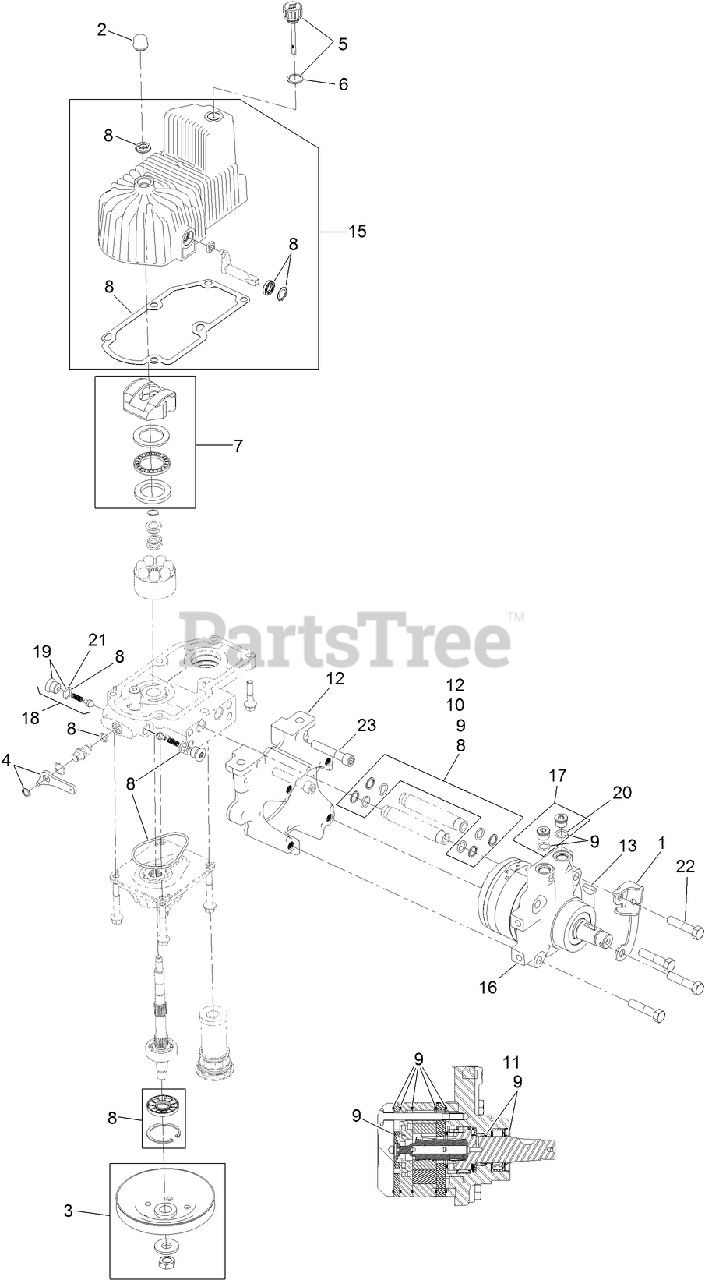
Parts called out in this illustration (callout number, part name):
1	BRACKET-ANCHOR, CABLE
2	COVER-SHAFT, HYDRO
3	PULLEY KIT
4	HANDLE-BYPASS VALVE, HYDRO
5	DIPSTICK-HYDRO W/GASKET
6	GASKET-DIPSTICK, HYDRO
7	SWASH BLOCK KIT
8	PUMP SEAL KIT
9	MOTOR SEAL KIT
10	TUBE SEAL KIT
11	OUTPUT SHAFT SEAL KIT
12	NOSE CUP-UHT
13	KEY-WOODRUFF
15	Housing-RH
16	MOTOR-HYDRAULIC RH 240CC
17	MAGNETIC PLUGS SERVICE KIT
18	CHECK VALVE ASM
19	PLUG-CHECK (W/O-RING)
20	O-RING
21	O-RING-CHECK VALVE
22	SCREW HH
23	SCREW-HSH
